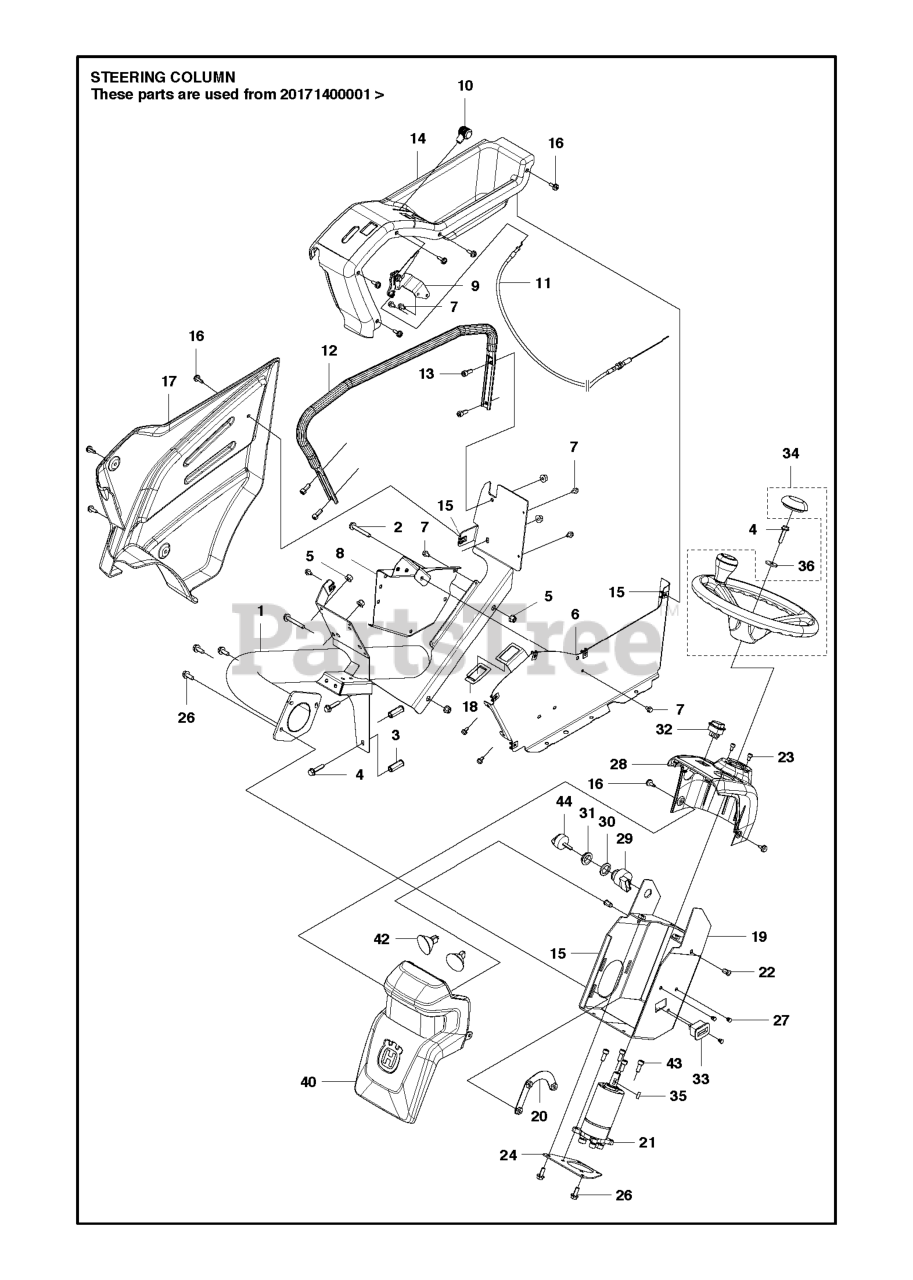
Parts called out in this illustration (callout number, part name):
2	SCREW EHHFM
4	SCREW EHHFM
5	NUT FLANGE
27	INSERT PIPE END
